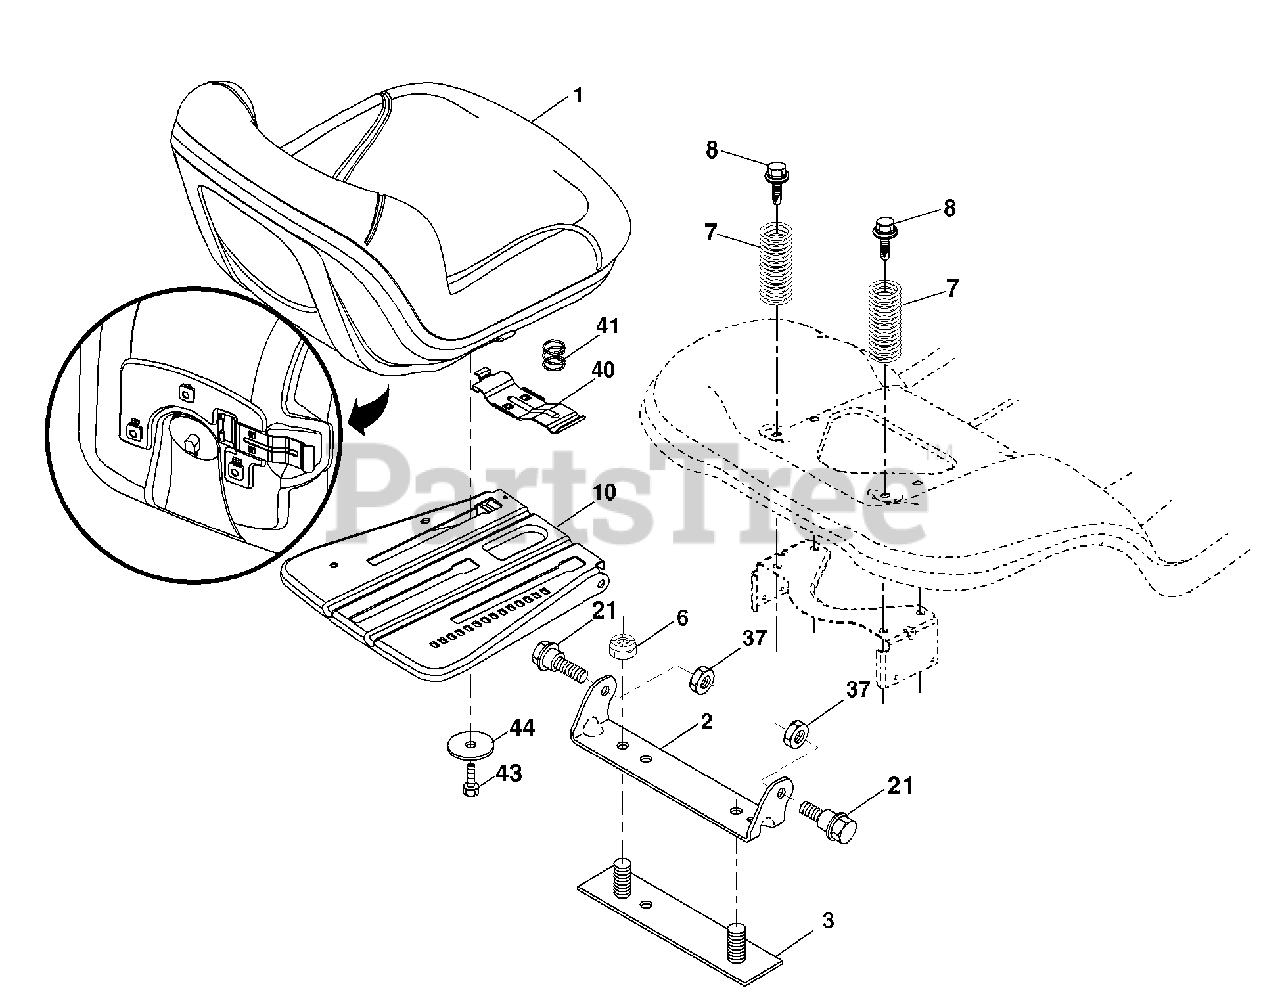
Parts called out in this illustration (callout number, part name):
1	Seat
2	Bracket Pivot Fender
3	Strap, Asm Fender
6	Nut, Lock W/Ins. 3/8-16 unc
7	Spring, Seat Cprsn
8	Bolt 5/16-18 uncx 3/4 w/Sems
10	Pan, Seat
21	Bolt, Shoulder 5/16-18
37	Nut, Lock 5/16-18 unc
40	Handle Slide
41	Spring Latch
43	Bolt 3/8-16 UNC x 3/4
44	Washer 13/32 x 2 3/8 x 12 Ga.
